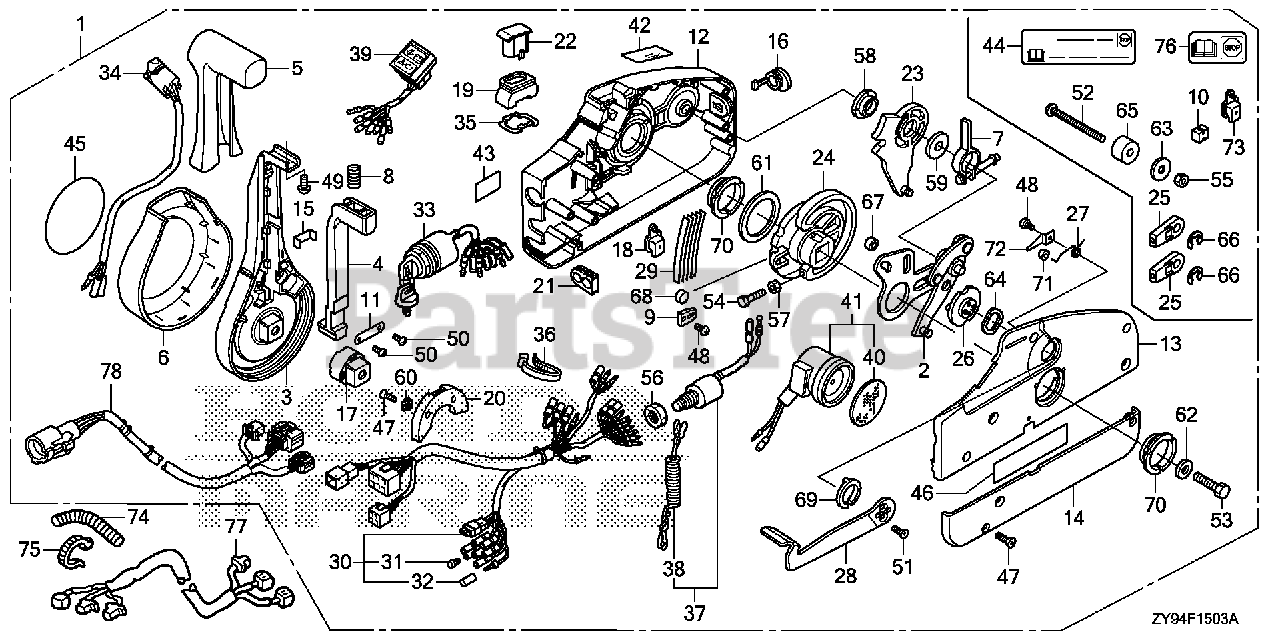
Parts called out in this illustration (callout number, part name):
1	BOX ASSY., REMOTE CONTROL (NHK MEC)
1	BOX ASSY., REMOTE CONTROL (TROLLING CONTROL)(NHK MEC)
2	PLATE ASSY.
3	LEVER, HAND
4	ARM, NEUTRAL LOCK
5	GRIP
6	COVER, LEVER
7	ARM ASSY., BRAKE
8	SPRING (2)
9	CLIP, DETENT
10	SPACER (1) (LOOSE PARTS)
11	BRACKET
12	HOUSING, FR.
13	HOUSING, RR.
14	PANEL, BACK
15	BRACKET, WIRE CLAMP
16	CAP, RUBBER
17	ADJUSTER
18	COVER, POWER TRIM-TILT WIRE (LOOSE PARTS)
19	SEAL, RUBBER
20	HOLDER, NEUTRAL LOCK
21	GROMMET, WIRE (14)
22	CAP, TROLLING CONTROL SWITCH BLANK
23	GEAR ASSY., SHIFT
24	GEAR, DRIVE
25	TERMINAL, CABLE (LOOSE PARTS)
26	DRUM ASSY., FREE THROTTLE
27	SPRING (1)
28	LEVER, FREE THROTTLE
29	SPRING, DETENT
30	CABLE ASSY., REMOTE CONTROL (B)
31	PLUG, CONNECTOR (INNER) (TROLLING CONTROL)
32	PLUG, CONNECTOR (OUTER) (ENGINE NO.)
33	SWITCH ASSY., COMBINATION (SINGLE) (DUAL)
34	SWITCH ASSY., POWER TRIM-TILT
35	PLATE, SWITCH
36	BAND, WIRE
37	SWITCH ASSY., EMERGENCY STOP
38	WIRE, EMERGENCY (SINGLE) (DUAL)
39	LAMP ASSY., INDICATION (2-LED)
39	LAMP ASSY., INDICATION
40	PLATE, TURN SIGNAL BUZZER DUAL QTY = (2) (SINGLE)
41	BUZZER, WARNING DUAL QTY = (2) (SINGLE)
42	MARK, FAST IDLE
43	MARK, EMERGENCY STOP (US) (LOOSE PARTS)
44	MARK, EMERGENCY STOP (US) (LOOSE PARTS)
45	MARK, EMBLEM
46	LABEL, SIGP
47	SCREW (5X18)
48	SCREW (4X6)
49	SCREW (5X10)
50	SCREW (4X10)
51	SCREW (5X12)
52	SCREW (6X90) (LOOSE PARTS)
53	BOLT (8X50)
54	BOLT (5X25)
55	NUT (6MM) (LOOSE PARTS)
56	NUT, HEX. (16MM) DUAL QTY = (2) (SINGLE)
57	NUT (5MM)
58	BEARING (1)
59	WASHER (3)
60	WASHER (4)
61	WASHER (5)
62	WASHER (8MM)
63	WASHER (7) (LOOSE PARTS)
64	WASHER, WAVE
65	SPACER (2) (LOOSE PARTS)
66	E-RING (6MM) (LOOSE PARTS)
67	ROLLER, DRIVE GEAR CAM
68	ROLLER
69	BEARING (2)
70	BEARING (3)
71	ROLLER, FREE THROTTLE
72	CLIP, ROLLER
73	COVER, POWER TRIM-TILT WIRE (LOOSE PARTS)
74	TUBE, CORRUGATED (28MM)
75	BAND, SELF-LOCK Use from Frame SN 3000253.
77	CABLE ASSY., REMOTE CONTROL EXTENSION Use from Frame SN 1300029.
78	CABLE ASSY., SWITCH PANEL
